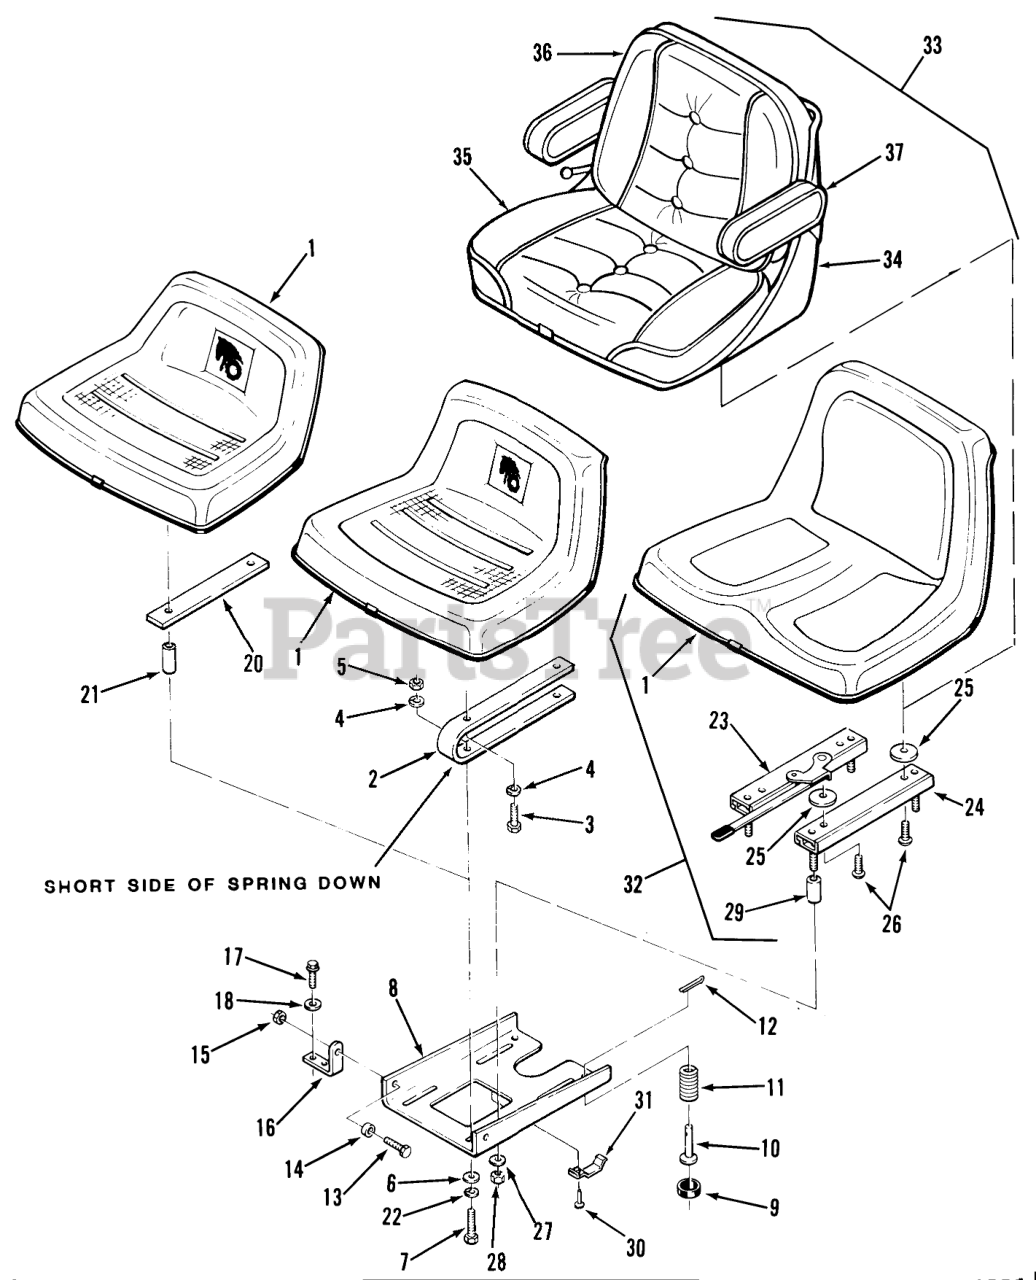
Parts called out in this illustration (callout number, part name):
1	Seat
2	Seat Spring
3	Bolt
4	Lockwasher
5	Nut
6	Collar
7	HHCS
8	PLATE SEAT PIVOT B
11	SPRING
12	Cotter Pin
13	HHCS
14	BUSHING
15	Nut
16	BRACKET-PIVOT
17	Bolt
18	WASHER 5/16 SAE
20	BAR SEAT SUPPORT B
21	SPACER SEAT B
22	Lockwasher
23	ADJUSTER-SEAT RH
24	ADJUSTER-SEAT LH
25	SPACER-NYLON
26	Screw
27	Collar
28	Nut
29	SPACER
30	RIVET
31	SPRING SWITCH
32	Deluxe Seat Assy (includes items 1, 23, 24, 25, 26 & 29)
33	Deluxe Leather Seat (includes items 23, 24, 25, 26, 34, 35, 36, & 37) 420-LSE Only
34	Leather Seat Pan 420-LSE Only
35	Leather Seat Cushion 420-LSE Only
36	Leather Seat Back Cushion 420-LSE Only
37	Leather Seat Arm Rest 420-LSE Only
